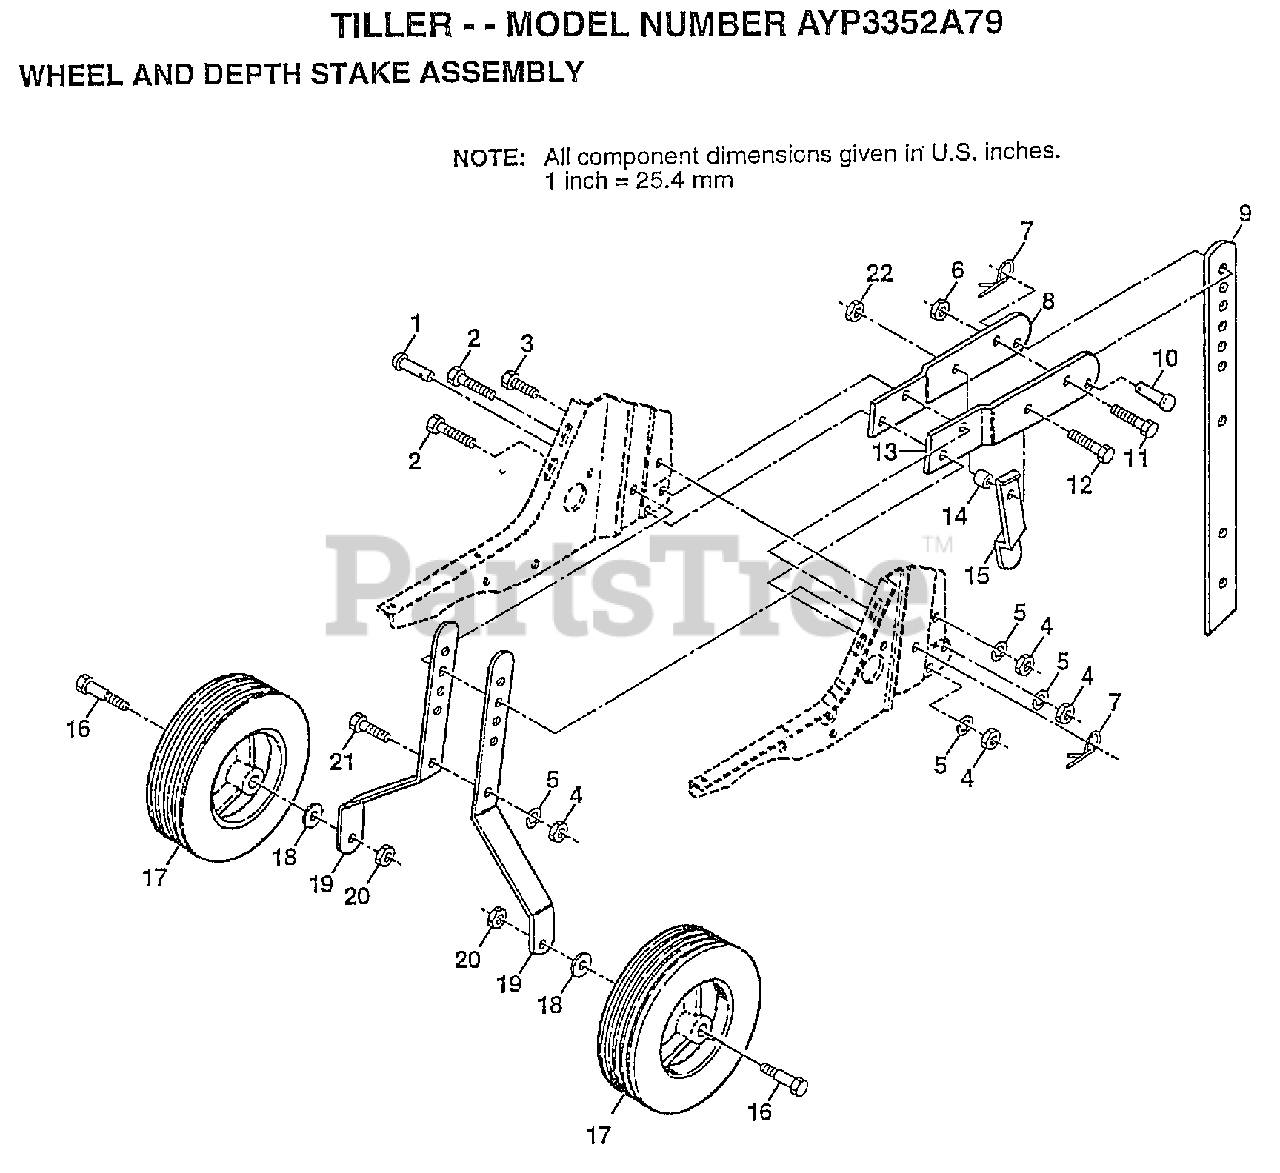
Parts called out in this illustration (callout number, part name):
1	DRILLED RIVET RT
3	BOLT
4	NUT.HEX.5/16-18
5	LOCKWASHER
6	NUT
7	SPRING.RETAINER
11	BOLT
12	BOLT.HEX.5/16-1.5
13	SUPPORT DEPTH STAKE LH
14	WASHER
15	STAKE SPRING TI
16	BOLT SHOULDER
18	WASHER
22	NUT
